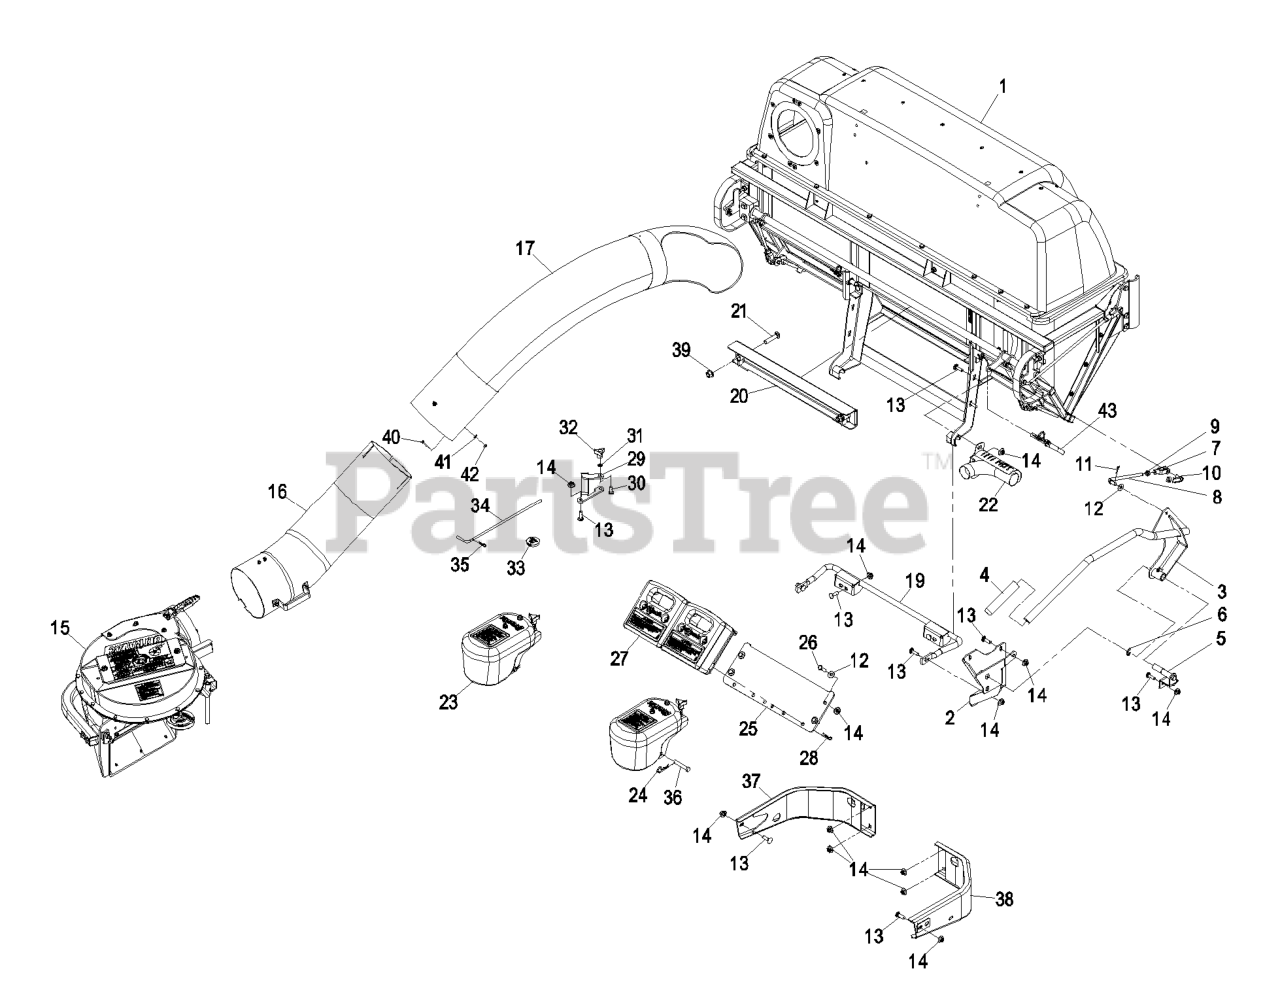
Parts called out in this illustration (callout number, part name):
1	Asm, Hopper
2	MOUNT-PIVOT
3	WLD,DUMP HANDLE
4	HANDLE-GRIP
5	PIN-HANDLE
7	YOKE-LINKAGE, BRAKE
8	LINK-HANDLE
9	NUT-HEX
10	PIN-SPRING, CLEVIS
11	PIN-COTTER
12	WASHER-FLAT
13	Bolt-Carriage 3/8-16 X 1 1/4
14	Nut-Nyloc 3/8-16 Flg
15	ASM, BLOWER LARGE - SVC O
16	LOWER TUBE ASM
17	TUBE-UPPER
19	MOUNT-BAGGER, LOWER
20	MOUNT-BAGGER, UPPER
21	SCREW-CARR
23	ASM,CASTER WEIGHT
24	PIN-COTTER
25	PLATE,WEIGHT ASM MOUNT
26	SCREW-HH
27	ASM,CAST WEIGHT
28	PIN-HAIR
29	BRACKET,BELT COVER
30	BOLT-CARR
31	RING-RETAINING, BOLT
32	KNOB-3 PRONG
33	PLUG, BLACK NYLON 1.75
34	PIN,CHUTE PIVOT
35	PIN-COTTER
36	PIN-CLEVIS
37	BUMPER-RH
38	LH BUMPER ASM
39	Nut-Lock 1/2-13
40	SCREW-HWH
41	WASHER-FLAT
42	NUT-LOCK, NI
43	PIN-MOUNT, BAGGER
